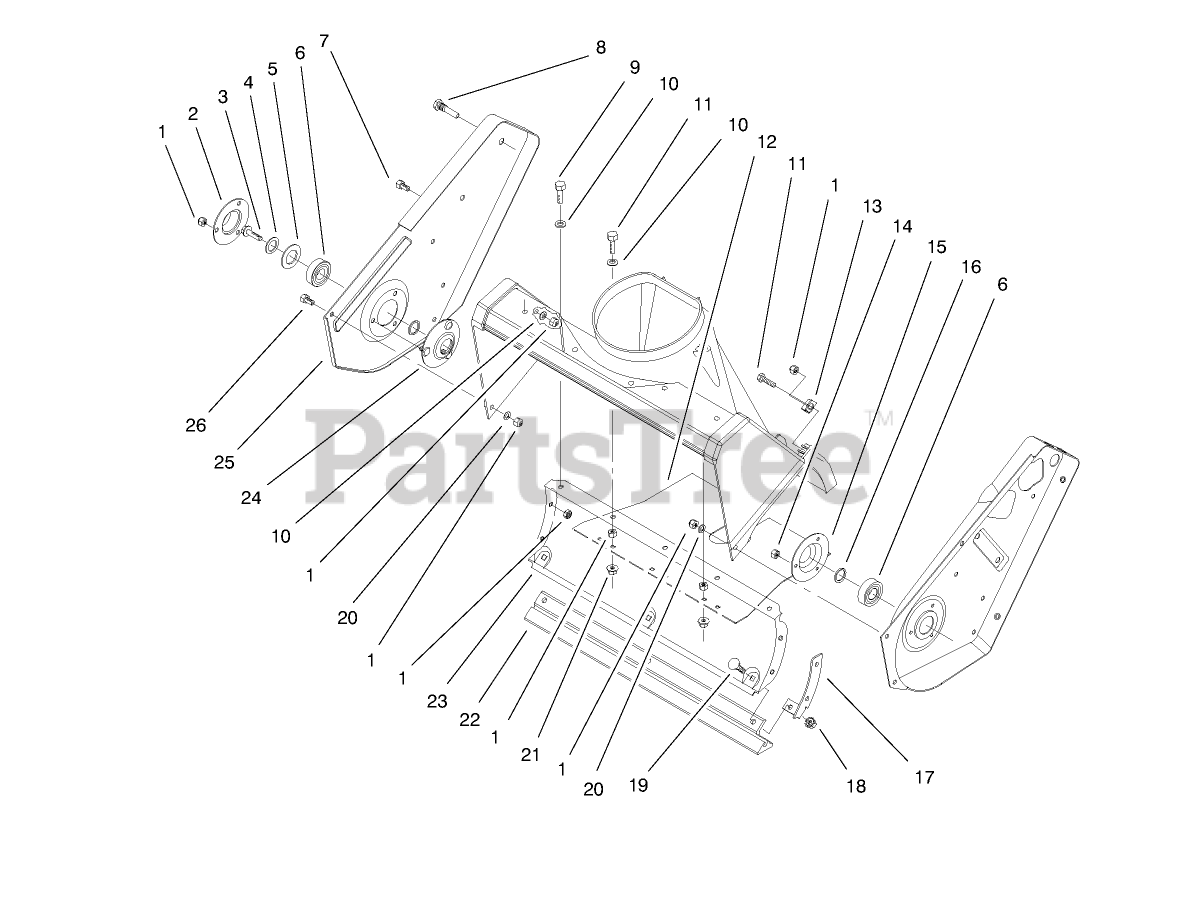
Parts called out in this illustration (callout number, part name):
1	NUT-LOCK, NI
3	SCREW-HHF
4	WASHER-FLAT
5	WASHER-RUBBER
6	BEARING-BALL
7	SCREW-HH
8	PIN-ROTOR
9	SCREW-HH
10	WASHER-FLAT
11	SCREW-HH
12	COVER-BOTTOM
13	BRACKET-HOUSING
14	NUT-LOCK, NI
15	FLANGE-BEARING
16	WASHER-THRUST
17	BRACKET-HOUSING, LOWER
18	NUT-KEPS
19	SCREW-CARR
20	WASHER
21	NUT-LOCK, HHF
22	SCRAPER
24	FLANGE-BEARING
26	SCREW-HWH
